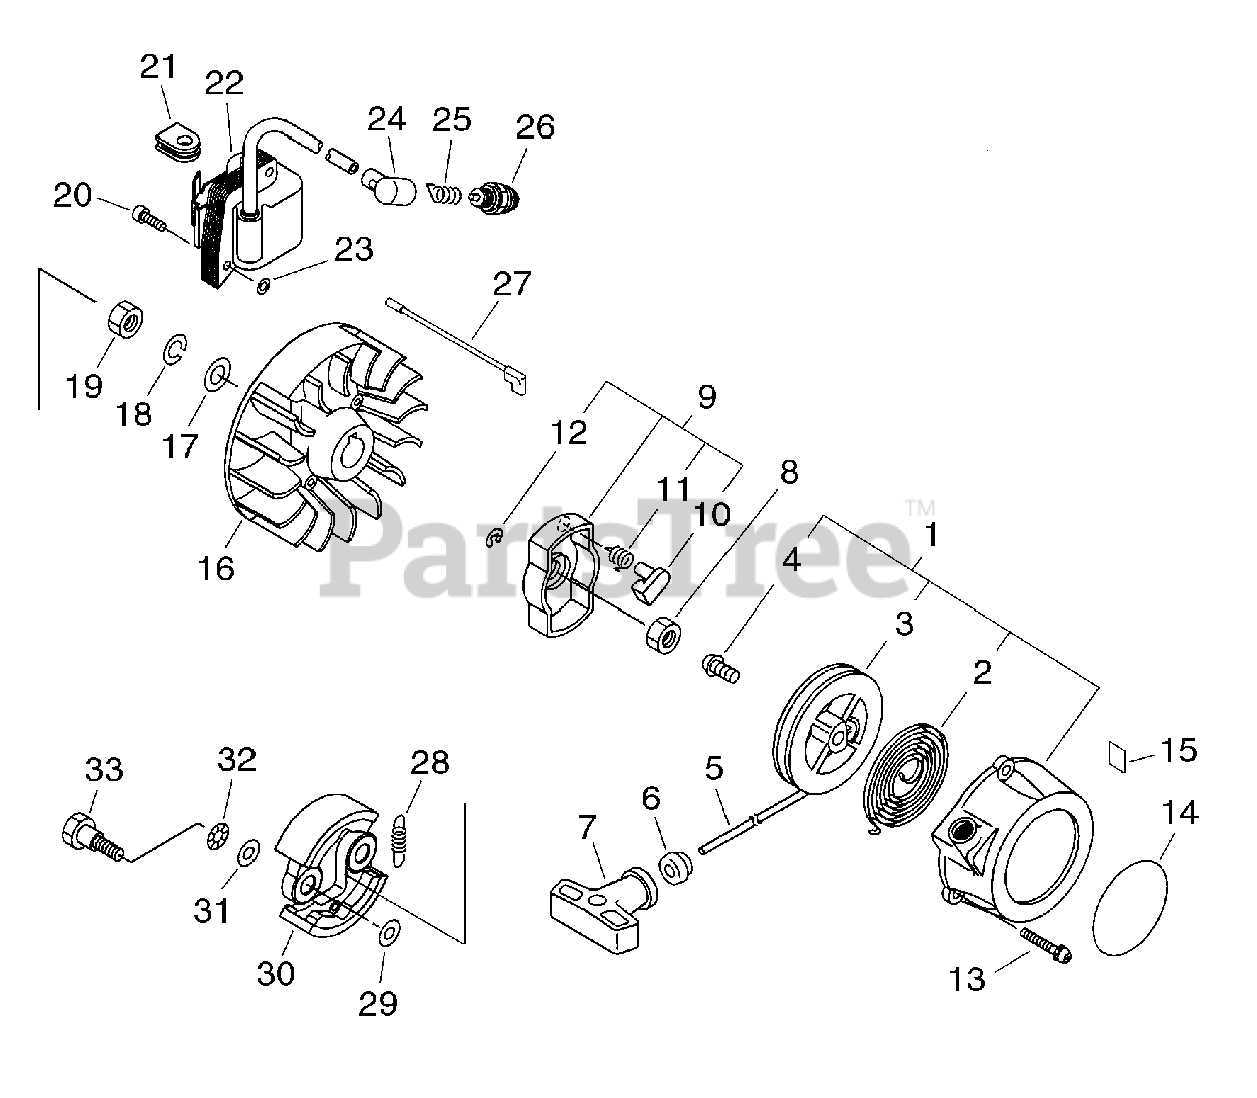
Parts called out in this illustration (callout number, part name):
1	Starter Asy
2	Spring, Rewind
3	Drum, Starter
5	Rope, Starter
6	Guide, Rope
7	Grip, Starter
8	Nut 8 (3n)
9	Pawl Asy, Starter
10	Rachet
11	Spring, Return
13	Screw 4x14
14	Label,echo
15	Label,caution
16	Rotor, Magneto
17	Washer 8
18	Washer, Spring 8
19	Nut 8 (3n)
20	Bolt Hsh
22	Coil, Ignition
24	Cap, Spark Plug
25	Coil, Spark Plug
26	Plug, Spark (BPM-7y)
28	Spring,tension
29	Washer,circular 6
30	Shoe, Clutch
31	Washer,Circular 8
33	Shaft, Clutch
